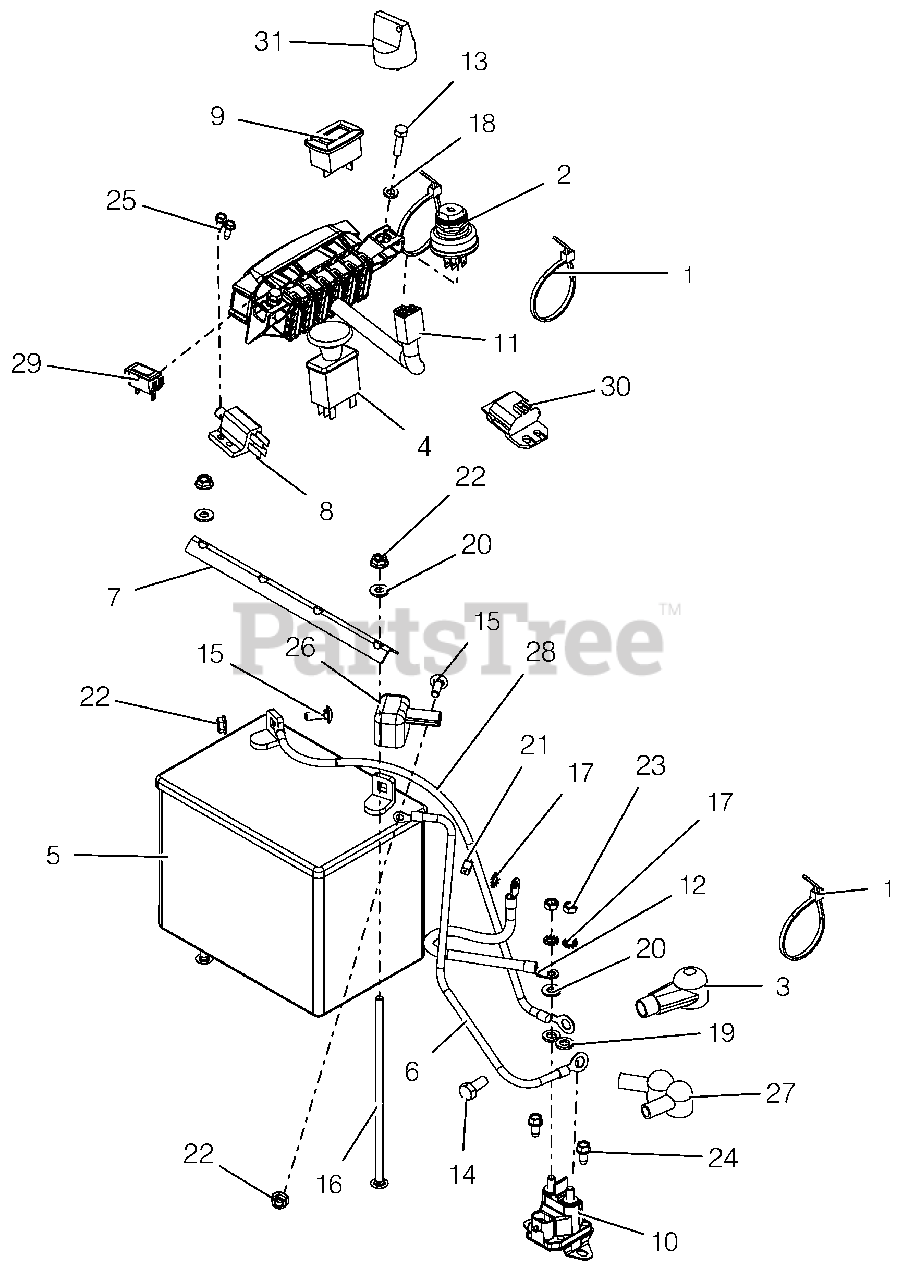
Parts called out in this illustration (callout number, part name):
1	CABLE TIE, .15 X 8.50
2	SWITCH, IGNITION
3	BOOT, BATTERY TERMINAL-RED
4	SWITCH, CLUTCH
5	BATTERY, 300 CCA 10U1L
6	CABLE, STARTER 13.00"
7	HOLD DOWN
8	SWITCH- DOUBLE POLE N.O./N.O.
9	METER, HOUR W/MAINTENANCE
10	SOLENOID, STARTER (SEALED)
11	HARNESS, PROSTANCE WIRING
11	FUSE,10 AMP MINI-ATC
11	FUSE,15 AMP MINI-ATC
11	FUSE,20 AMP MINI ATC
11	RELAY,MICRO5 TERML W/RESISTOR
11	DIODE, CONNECTOR SHELL
11	FUSE, 20 AMP BLADE S/O
12	CABLE, POS W/(2)1/4 RING 9.0LG
13	@BLT-HEX M6-1.0X25 YWZC
14	@BLT-HEX M8-1.25X20 YWZC
15	@BLT-RDHDSQNK .25-20X.75 G5YZ
16	BLT-RDHDSQNK .25-20X7.50 GR2YZ
17	@WSHR-LK-EXT.262X.502X.026YWZC
18	@WSHR-LK .25X.062 REG YWZC
19	@WSHR-LK .31X.078 REG YWZC
20	@WSHR-FL-STL.281X.62X.065 YWZC
21	@NUT-LK-CTR .25-20 YWZC
22	@NUT-SPNLK-FLG .25-20 YWZC
23	NUT-HEX M6X1.0 YWZC
24	SCR-TAP .25-20X.50 HWH TR YWZ
25	@SCR-TAP 10-24X.50 HWH TR YWZC
26	INSULATOR
27	BOOT, EYELET TERMINAL
28	CBL,NEGATIVE BATTERY 20.00
29	LIGHT,INDICATOR
30	MODULE,INTERLOCK,DELAY, 1801
31	KEY, W/ SHIELD
